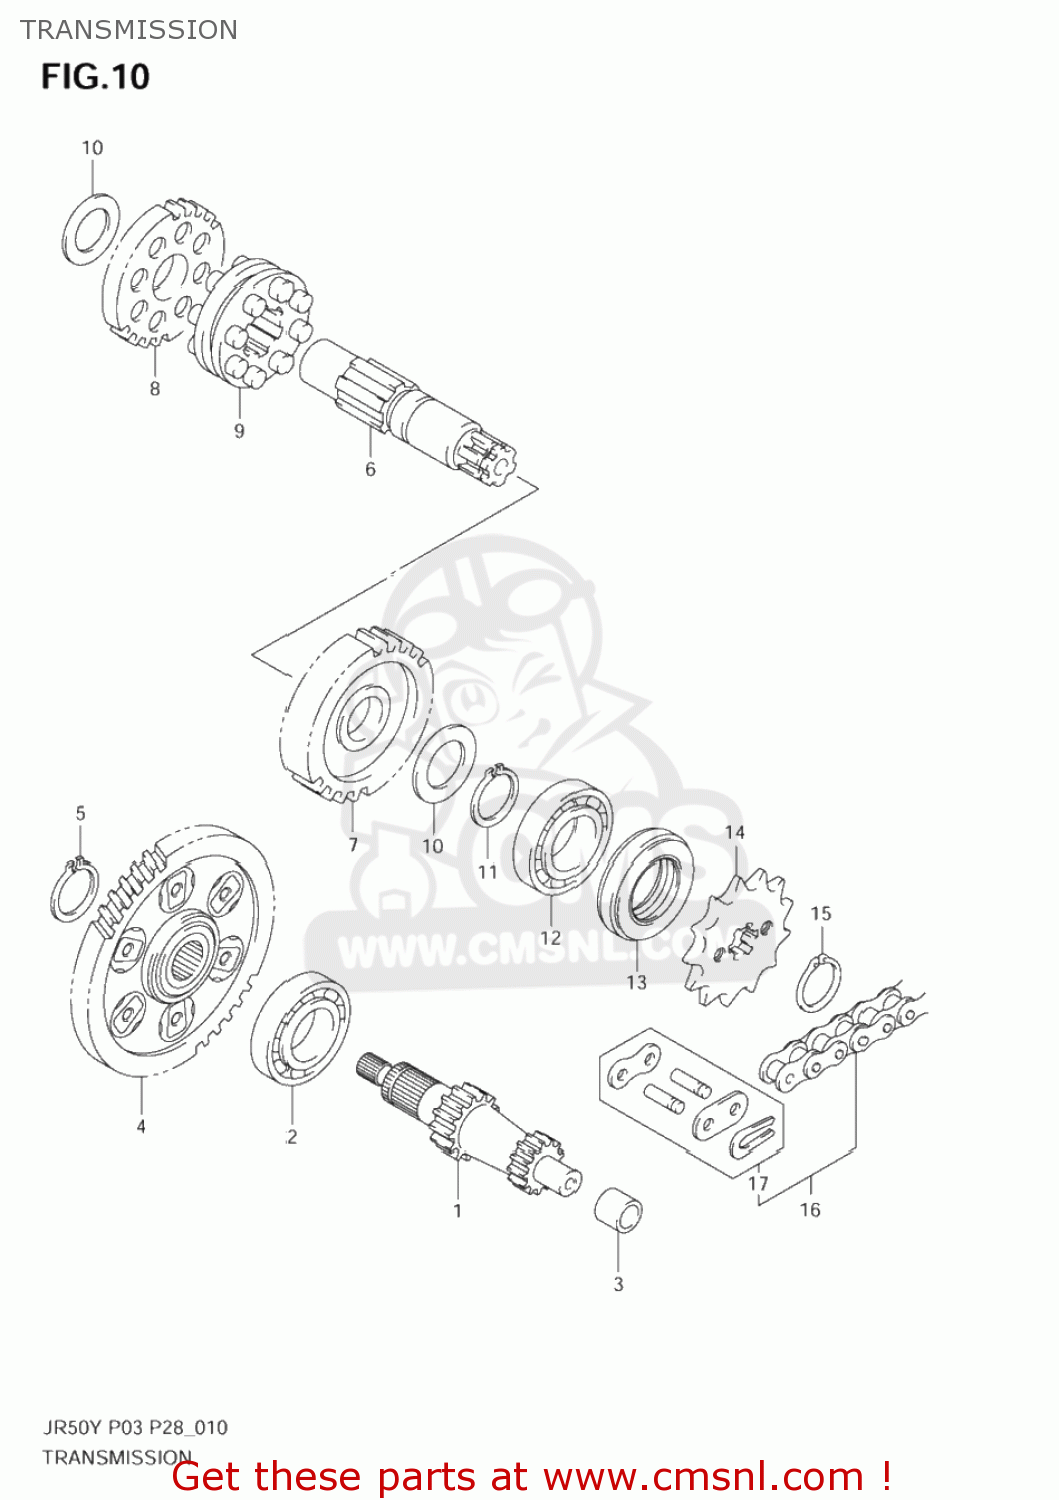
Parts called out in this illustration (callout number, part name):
1	SHAFT,COUNTER
2	BEARING(17X40X12)
3	BUSH
4	GEAR ASSY,PRI DRIVEN
5	CIRCLIP
6	SHAFT,DRIVE
7	GEAR 1ST DRIVEN
8	GEAR 2ND DRIVEN
9	WHEEL,1ST GEAR
10	SHIM(17X30X1)
11	CIRCLIP
12	BEARING(17X40X12)
13	OIL SEAL (17X29X7)
14	SPROCKET,ENGINE
15	CIRCLIP 16MM
16	CHAIN,DRIVE
17	JOINT
